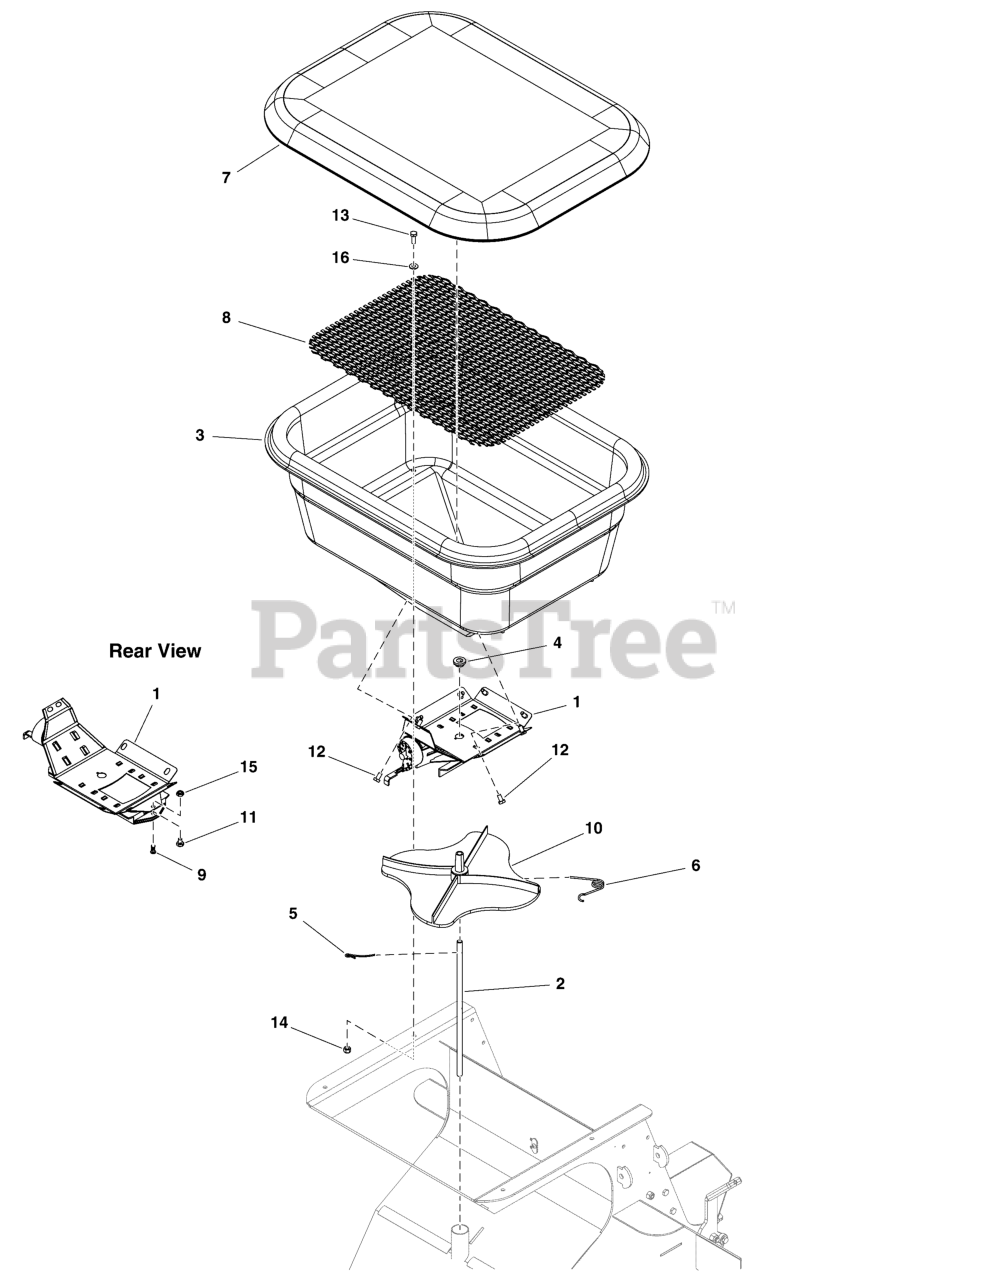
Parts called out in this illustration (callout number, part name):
2	KIT, PLATTER SHAFT COUPLING
2	SHAFT, Platter
2	SHAFT, PLATTER DRIVE (PATHFINDER/PATHFINDER XC)
3	HOPPER, 120 LBS
4	BUSHING, HOPPER SPREADER
5	CLIP, SPINNER AGITATOR
6	CLIP, SPREADER SPINNER
7	COVER, HOPPER, MODEL 120
8	SCREEN, HOPPER MODEL 120 LBS
9	FITTING, SWIVEL ACCUWAY
10	PLATTER, SPINNER, REDUCED CLEARANCE
11	SCR-CAP, HEX .250"-20 X .375" SS188 SPC
12	SCR-CAP, HEX .250"-20 X .500" SS188
13	SCR-CAP, HEX .250"-20 X .750" SS188
14	NUT-HEX-NYLK, .250"-20 SS188
15	NUT-HEX-NYLK, .250"-20 TH SS188
16	WSHR-STL, FLT .281" X .625" X .050" IS SS188
